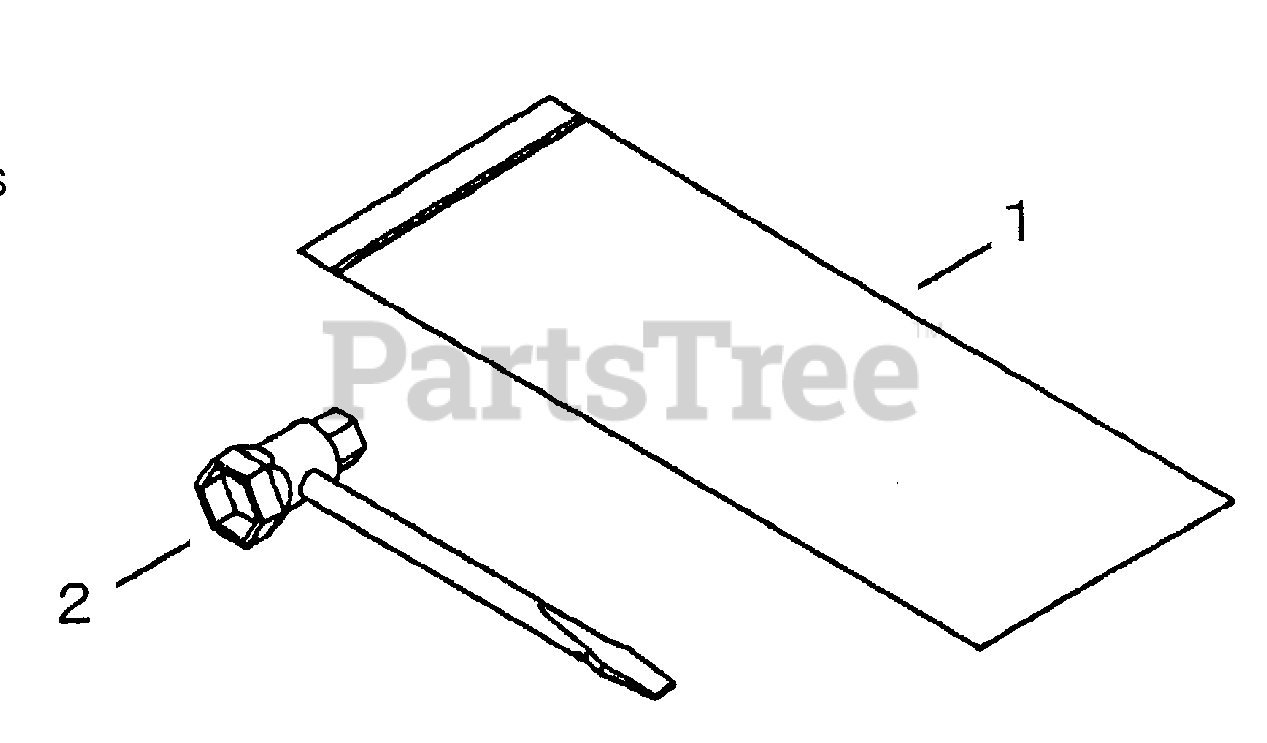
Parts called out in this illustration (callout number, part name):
1	BAG, TOOL
2	T-WRENCH - 13X19mm
3	HEX KEY - 4mm
